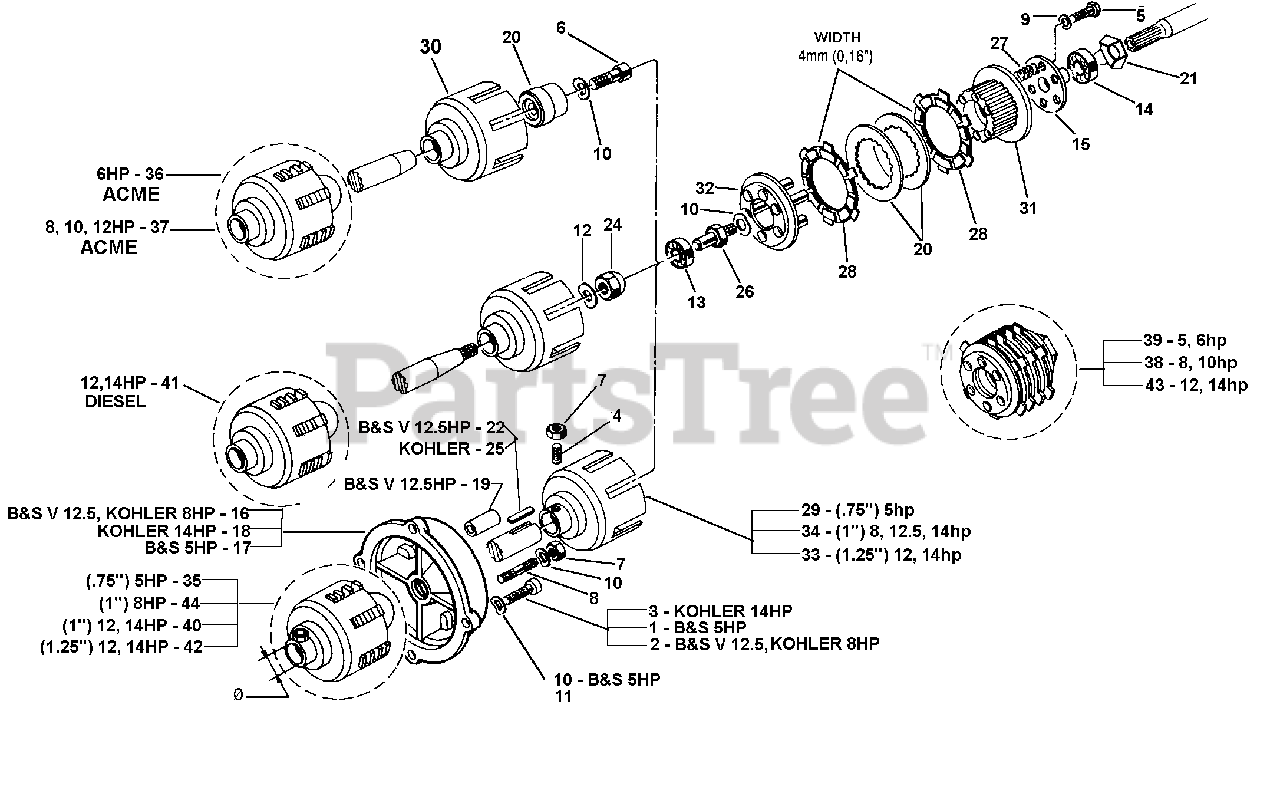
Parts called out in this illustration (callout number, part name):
1	SCREW 5/16 X 7/8
2	SCREW 3/8 X 1
4	SCREW M8 X 14
6	SCREW M8 X 25
8	STUD M8 X 40 X 14 X 14
9	SUPER WASHER
10	WASHER, LOCK 8.4
11	WASHER, LOCK 10.5
12	WASHER, LOCK 17
14	BEARING 17 X 40 X 12
15	CLUTCH FLANGE
16	FLANGE FOR KOHLER ENGINE 8HP
17	FLANGE FOR 5HP B&S
18	FLANGE FOR KOHLER ENGINE 14HP
19	TWIN SPACER B&S
20	INSIDE CLUTCH DISC
21	BEARING PLATE
22	KEY B&S 12.5HP
23	BEARING HOLDER BUSHING
24	SPECIAL NUT
26	SCREW 9 X 1
27	DISC CLUTCH SPRING
28	OUTSIDE DISC
29	CLUTCH BELL
30	CLUTCH BELL
32	CLUTCH BOTTOM
33	KOHLER CLUTCH BELL
34	CLUTCH BELL
35	DISC CLUTCH ASSEMBLY
36	DISC CLUTCH ASSEMBLY
37	DISC CLUTCH ASSEMBLY
38	DISC ASSEMBLY
39	DISC ASSEMBLY
40	DISC CLUTCH ASSEMBLY
41	DISC CLUTCH ASSEMBLY
42	DISC CLUTCH ASSEMBLY
43	DISC ASSEMBLY
44	DISC CLUTCH ASSEMBLY
